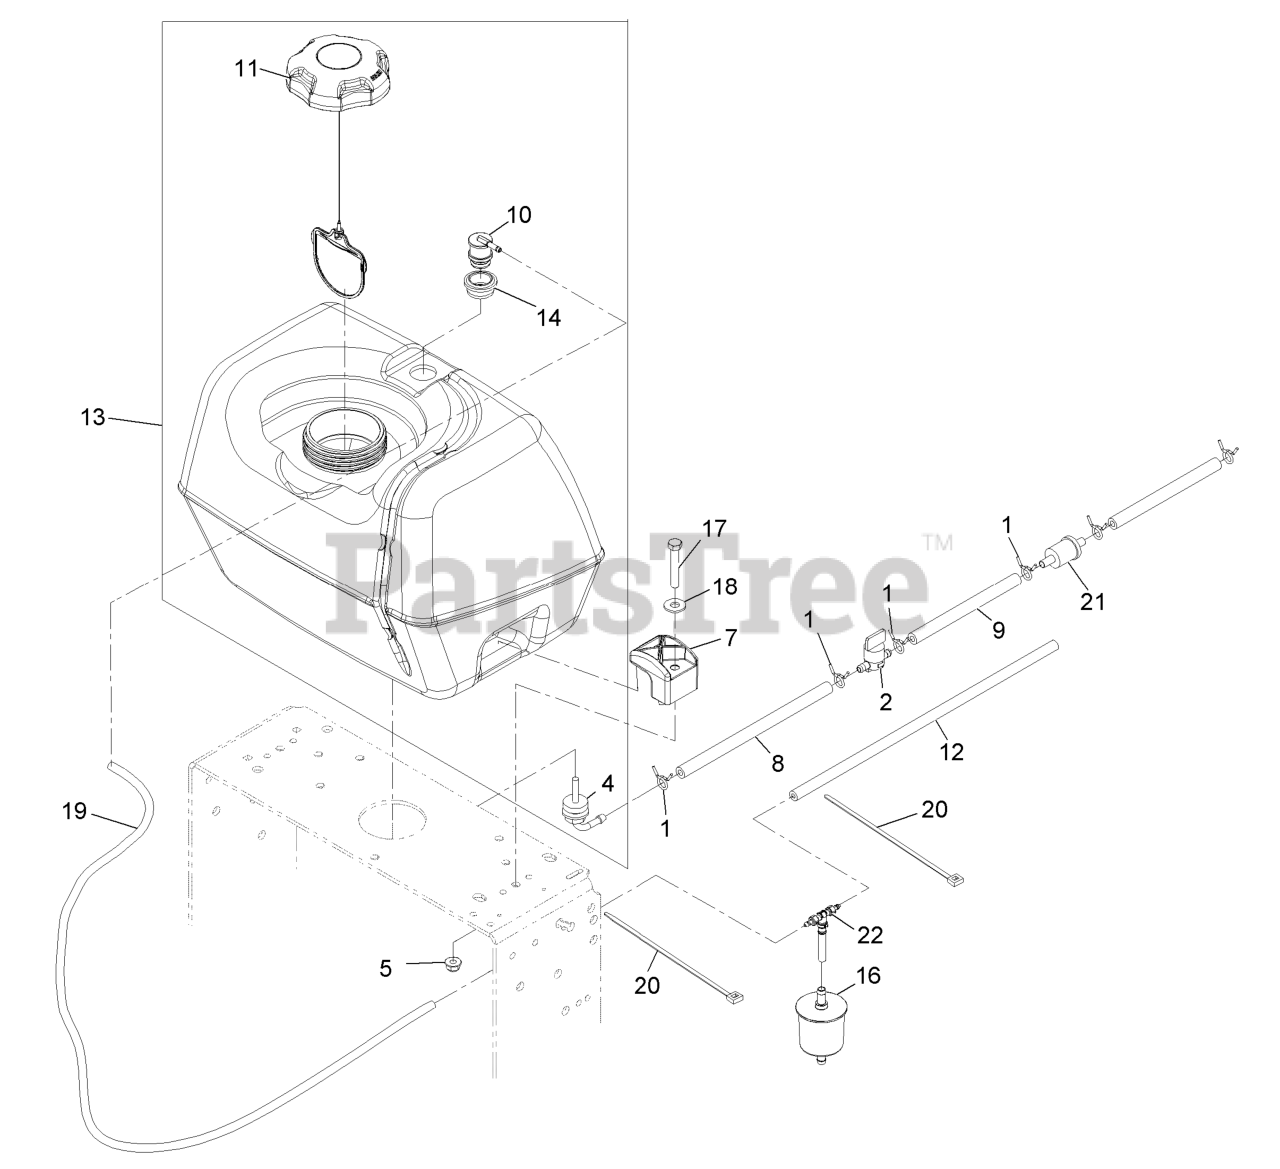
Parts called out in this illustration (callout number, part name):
1	CLAMP-HOSE
2	VALVE-FUEL
4	FITTING-FUEL, BULKHEAD
5	NUT-HF, NI
8	PLATE,SKID 605
9	HOSE-FUEL
10	VALVE-VENT, FUEL
12	HOSE-FUEL
13	ASM, FUEL TANK
14	GROMMET
16	FILTER-FUEL
17	SCREW-HH
18	WASHER-FLAT
19	HOSE-EMISSIONS
20	TIE-PLASTIC
21	Pn 41019-1055 Filter W/6in Fuel Line
22	TEE AND CHECK
